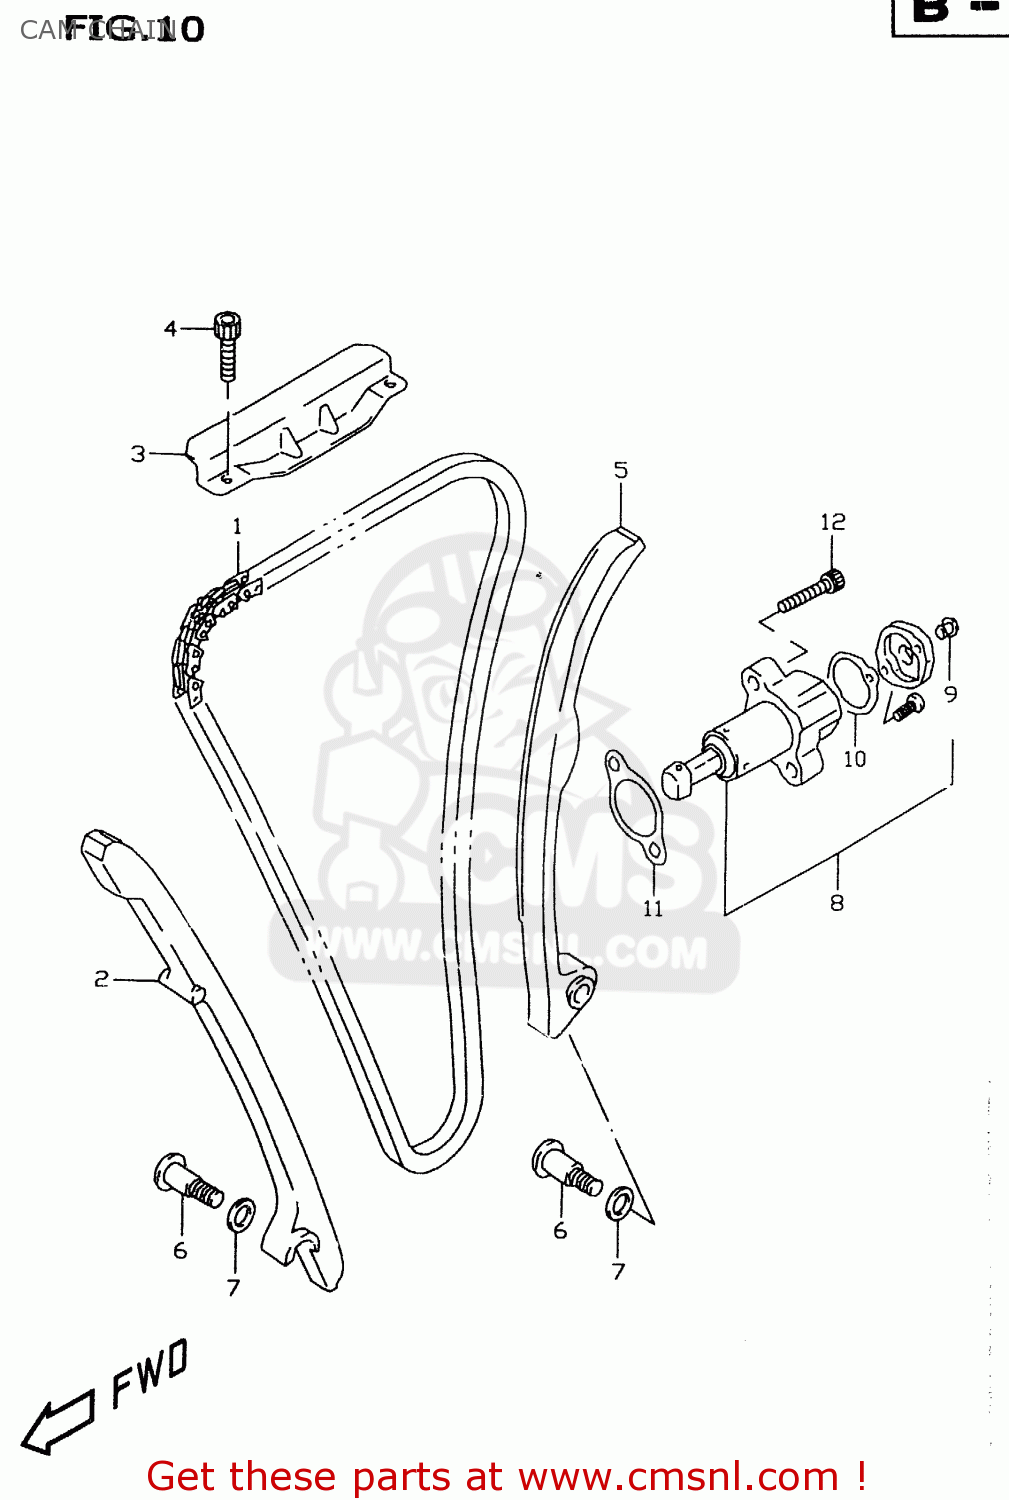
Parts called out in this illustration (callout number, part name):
1	CHAIN,CAMSHAFT DRIVE
2	GUIDE,CAM CHAIN NO.1
3	GUIDE,CAM CHAIN NO.2
4	BOLT,STRANGER
5	TENSIONER,CAM CHAIN
6	BOLT,CAM CHAIN TENSIONER
7	WASHER
8	ADJUSTER ASSEMBLY,TENSIONER
9	PLUG,ADJUSTER
10	GASKET,ADJUSTER CAP (NAS)
11	GASKET,TENSIONER ADJUSTER (NAS)
12	BOLT,CL.COVER
